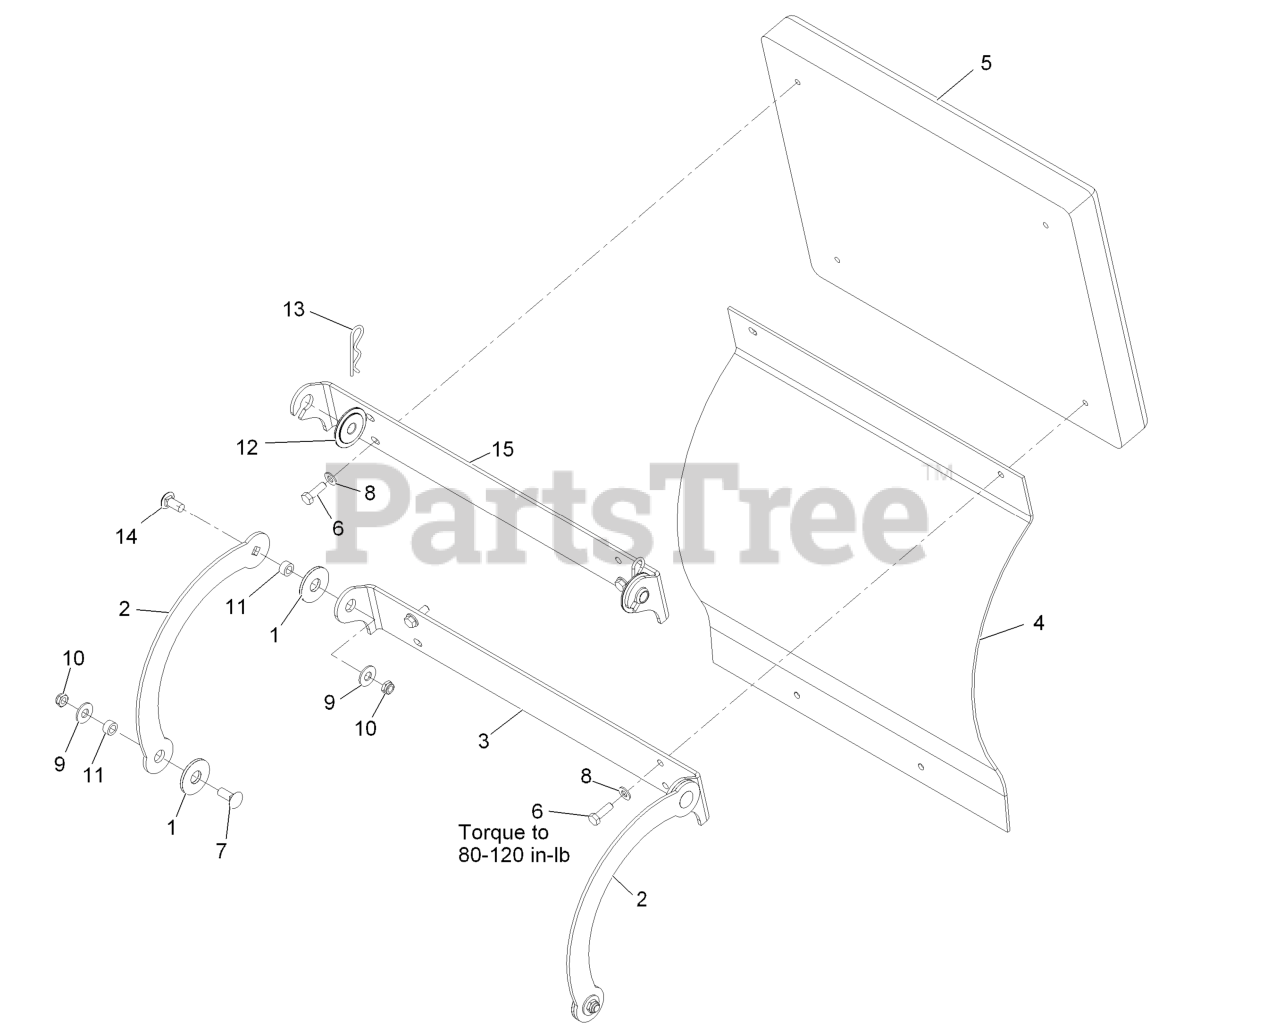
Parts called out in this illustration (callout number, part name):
1	WASHER-FRICTION, COMPOSIT
3	HINGE-PAD
5	PAD,GREY CUSHION
6	SCREW-HH, THREAD LOCKING
7	BOLT-CARR
8	WASHER-PLAIN
9	WASHER-FLAT
11	SPACER
12	SLIDE-BUSHING
13	PIN-HAIR
14	SCREW-CARR
15	HINGE-PAD
